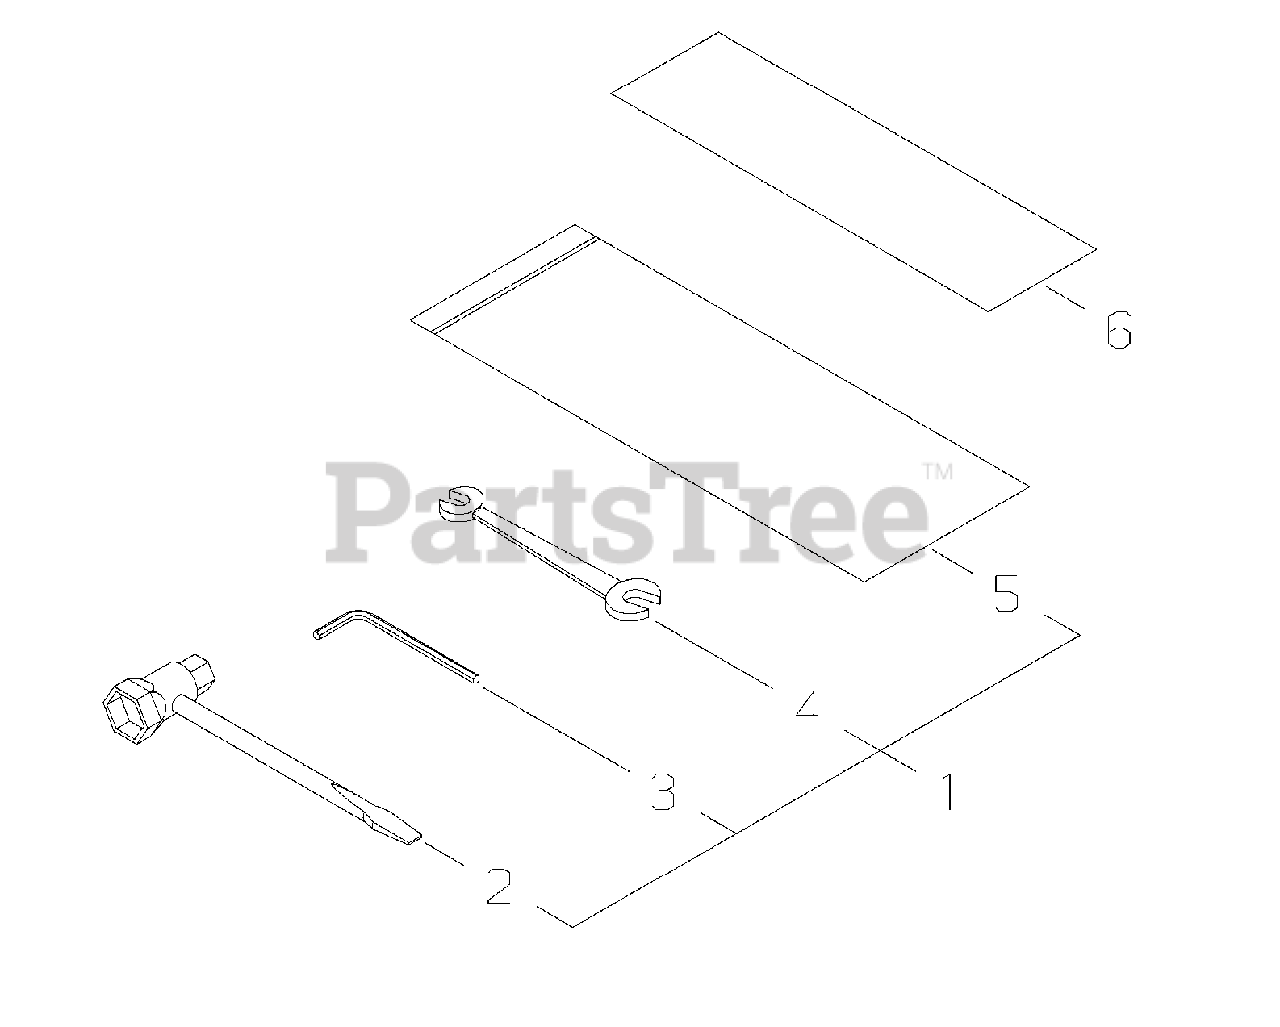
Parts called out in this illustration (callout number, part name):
1	TOOL KIT
2	T-WRENCH
3	WRENCH, ALLEN 4 MM
4	SPANNER 8×10
5	BAG, TOOL
6	LABEL, CAUTION
